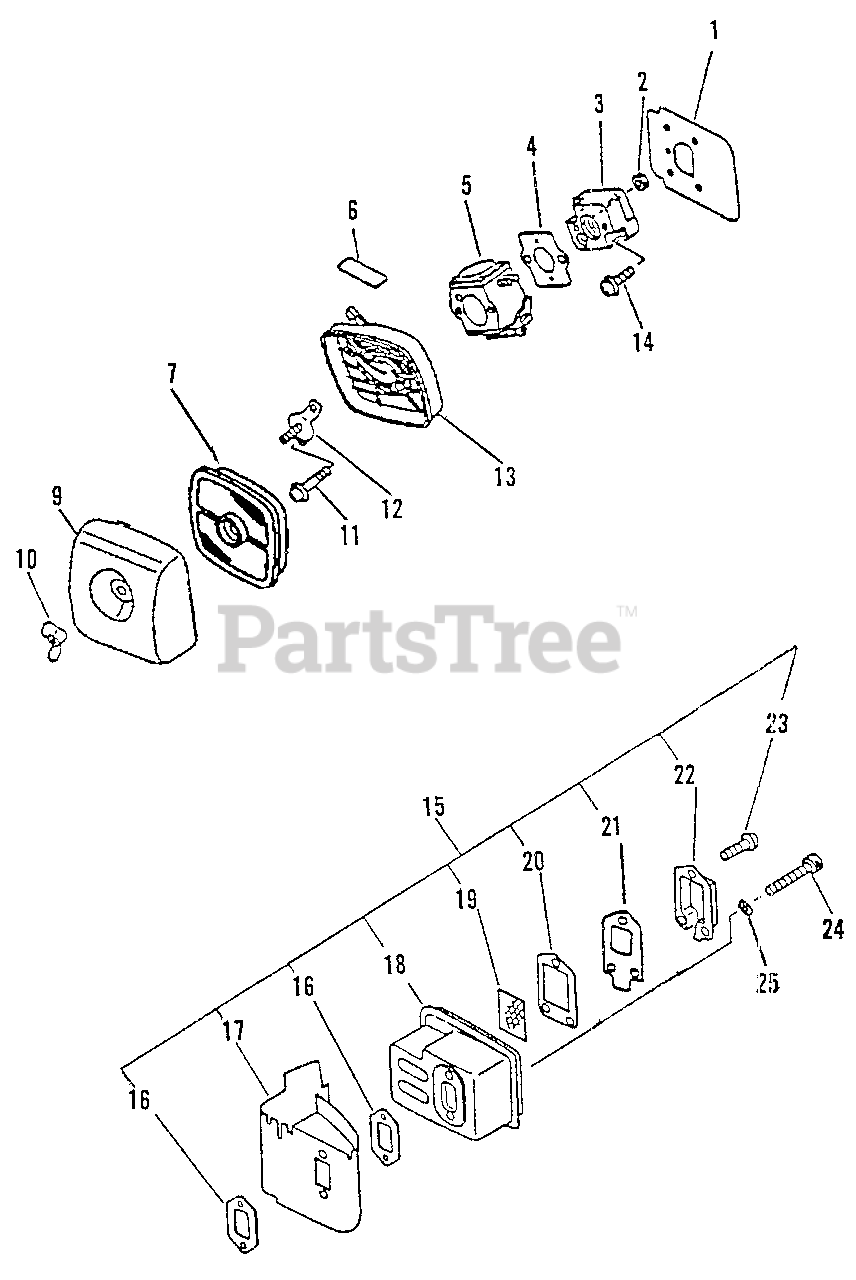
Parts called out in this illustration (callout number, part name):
1	HEAT SHIELD, INTAKE
2	NUT M5
3	INSULATOR, INTAKE
4	GASKET, INTAKE
5	CARBURETOR - C1U-K31A
6	LABEL, CHOKE
7	FILTER, AIR - SINGLE LAYER
9	COVER, AIR FILTER - BLACK
10	WINGNUT - 6
11	SCREW 5×65
12	PLATE, PREVENT
13	CASE ASSY, AIR FILTER
14	SCREW 5×20
15	MUFFLER ASSY
16	GASKET, EXHAUST
17	COVER, EXHAUST
19	SCREEN, SPARK ARRESTER
20	GASKET, EXHAUST
21	GUIDE, EXHAUST
22	GUIDE, EXHAUST - INNER
23	SCREW 4×10
24	BOLT 5×55
25	WASHER, FLAT 5.5×10×0.8
